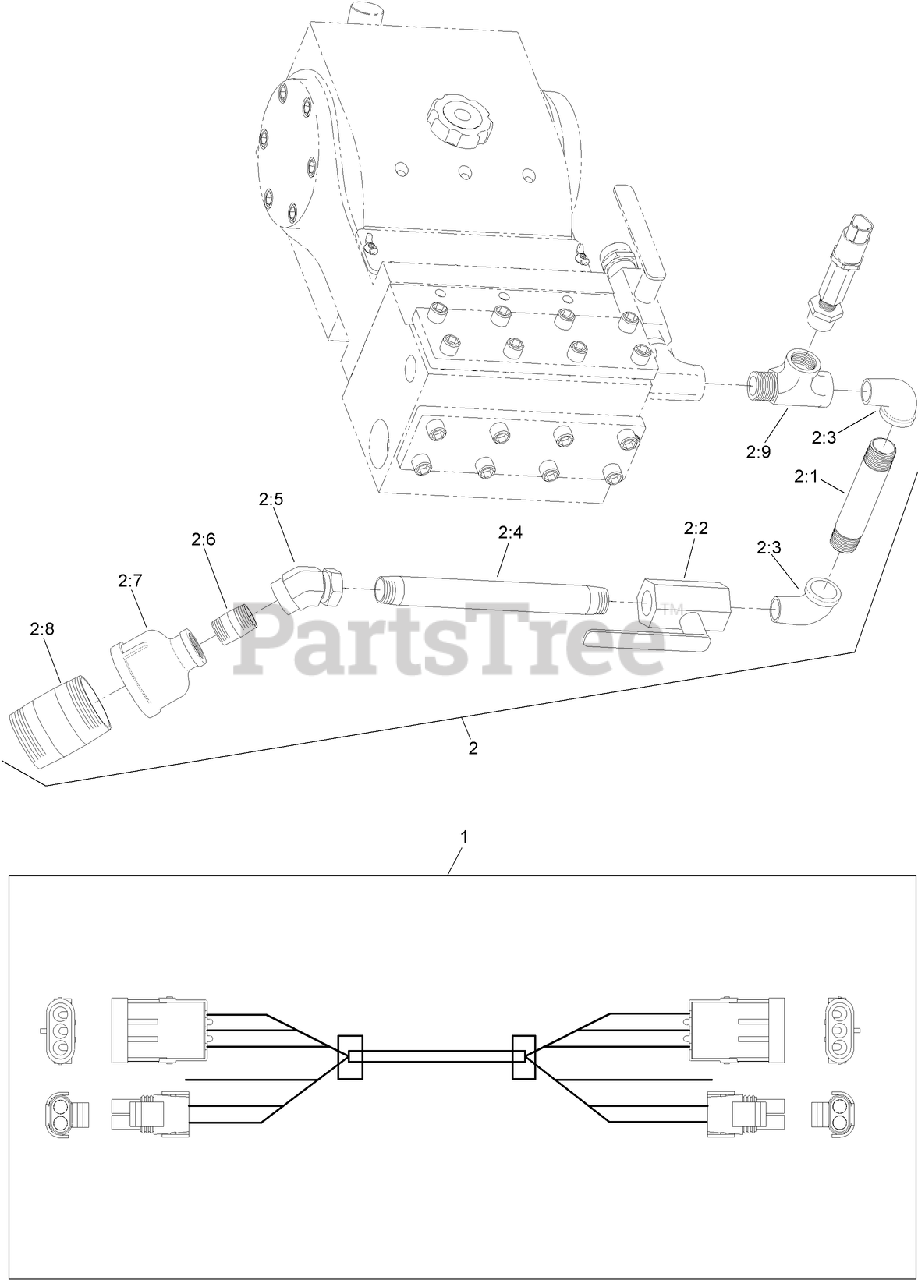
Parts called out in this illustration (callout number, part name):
1	HARNESS-AIR HAMMER
2:1	NIPPLE-PIPE
2:2	VALVE-BALL
2:3	ELBOW-STREET, 90 DEG
2:4	NIPPLE-PIPE
2:5	ELBOW-FEMALE, 45 DEG
2:6	NIPPLE-STRAIGHT
2:7	FITTING-BELL REDUCER
2:8	NIPPLE-PIPE
2:9	FITTING-TEE
